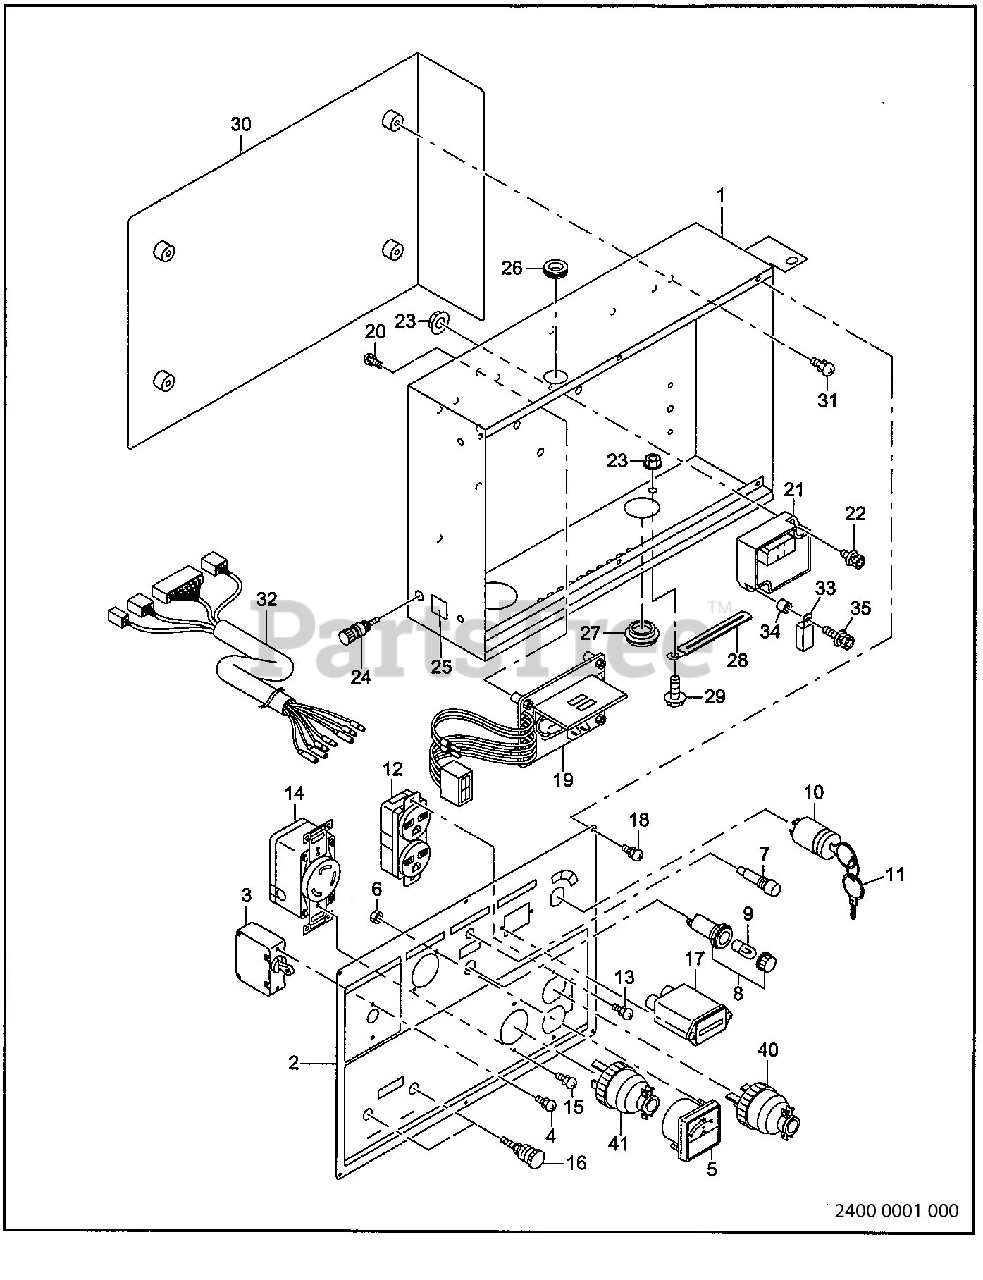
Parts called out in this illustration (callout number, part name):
1	CONTROL BOX ASSY
1	CONTROL BOX UNIT
2	CONTROL PANEL ASSY
3	BREAKER (1P-36A)
3	BREAKER (1P-35A)
4	SCREW and WASHER ASSY
8	LAMP (OIL)
9	LAMP (18V-0.11A)
10	KEY SWITCH
12	AC RECEPTACLE (250V-15A)
13	SCREW and WASHER ASSY
14	AC RECEPTACLE (250V-30A, TWIST LOCK)
15	SCREW and WASHER ASSY
16	TERMINAL
18	SCREW and WASHER ASSY
19	AVR ASSY
20	SCREW and WASHER ASSY
21	ECU(O/S & R/C) ASSY
22	SCREW and WASHER ASSY
23	FLANGE NUT
28	CLAMP
30	PLATE
31	SCREW and WASHER ASSY
32	WIRE ASSY
35	SCREW
40	AC PLUG (250V-15A)
41	AC PLUG (250V-30A)
